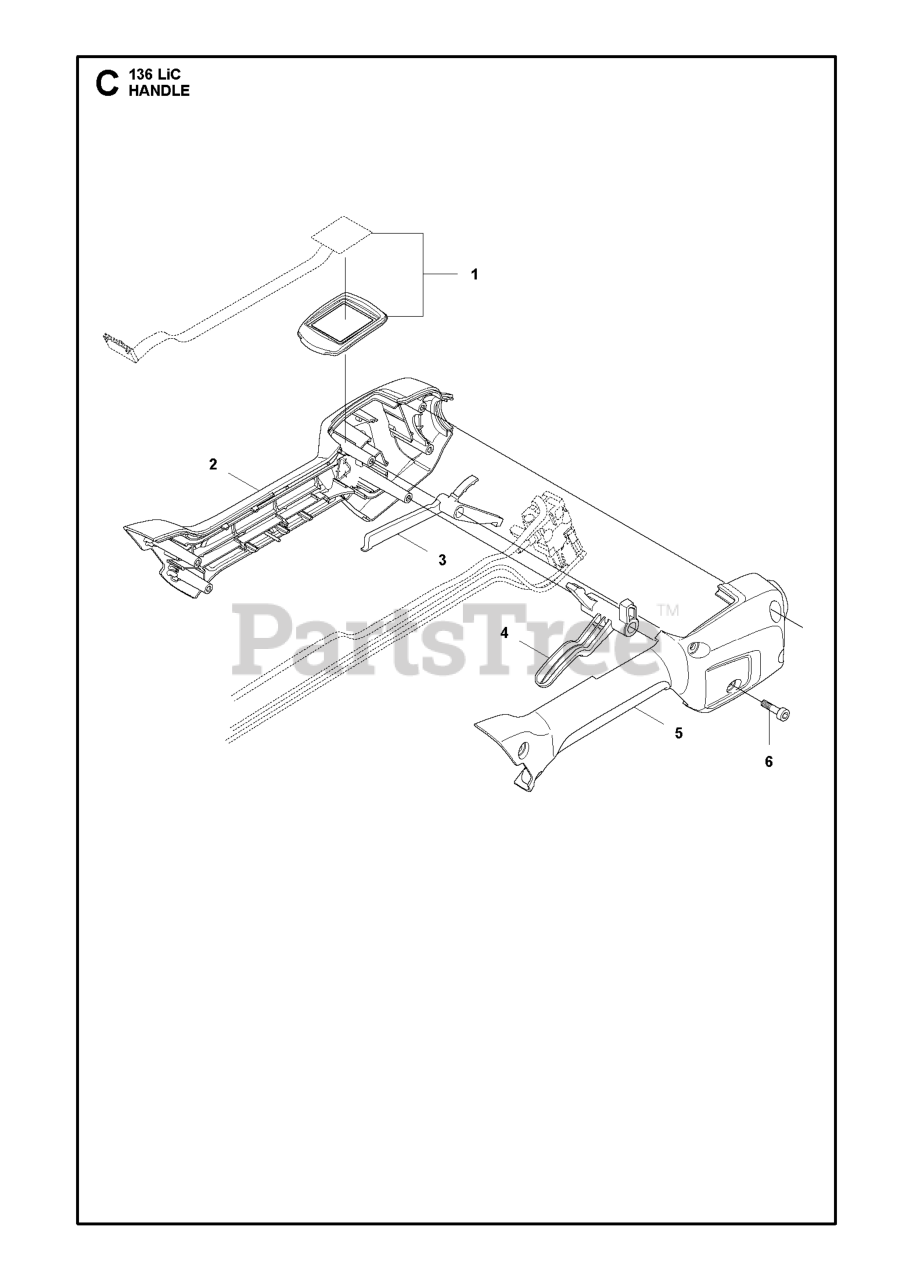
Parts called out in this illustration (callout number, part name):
2	HANDLE HALF LEFT
3	THROTTLE LOCKOUT
4	TRIGGER
5	HANDLE HALF RIGHT
6	SCREW
